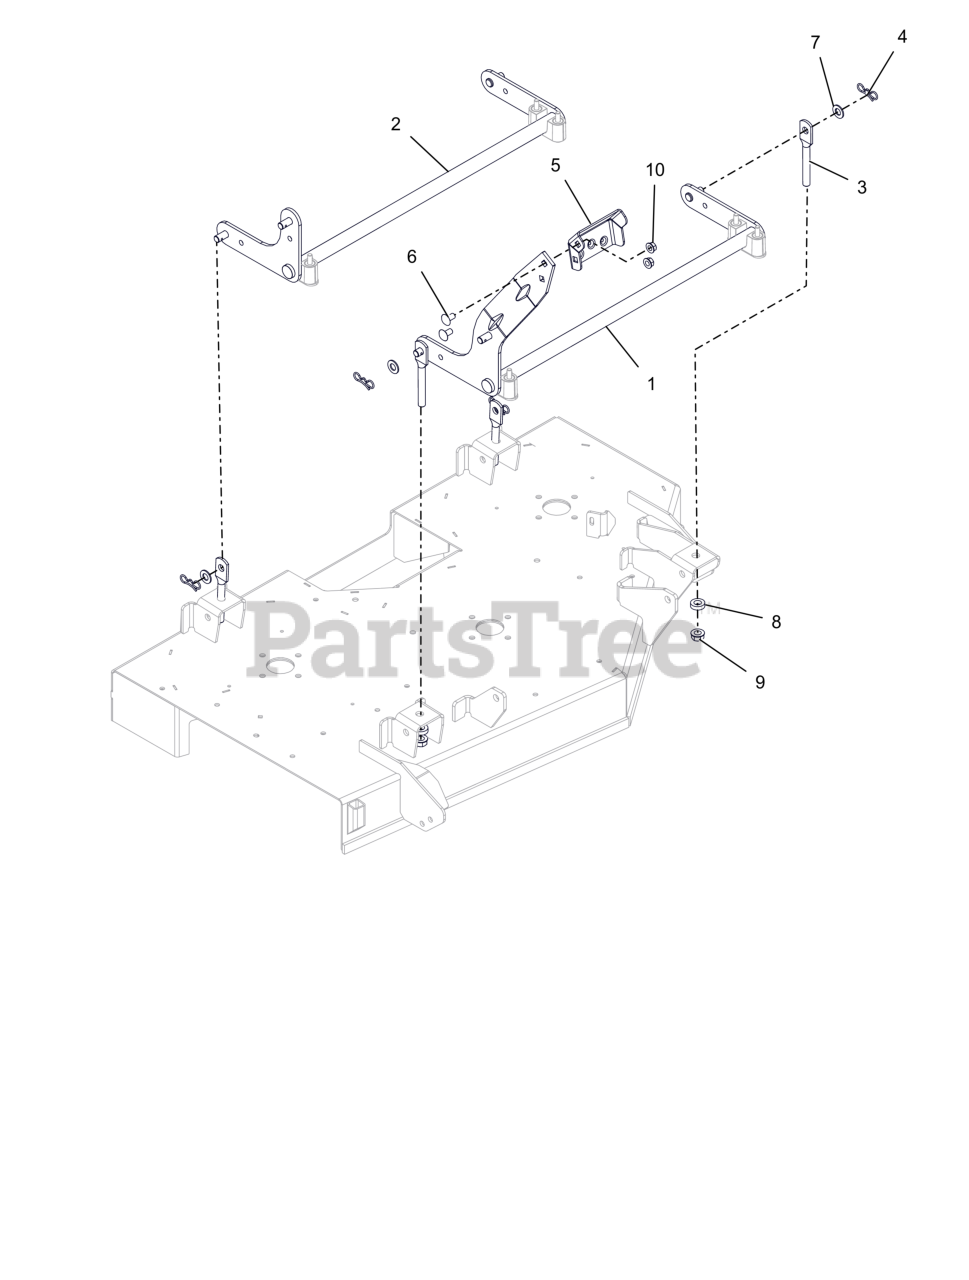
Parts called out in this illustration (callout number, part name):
1	WLDMT, FRONT DECK LIFT PIVOT
2	WLDMT, REAR DECK PIVOT
3	LINK, DECK (HOLE-LONG)
4	PIN, BOWTIE .091X1.875 ZCC
5	PEDAL, DECK LIFT (BOLT ON)
6	BTL,RHSSN .375-16 X 0.75 G5 FPB
7	WSHR-FL-NYL .518X1.000X.080
8	WSHR, RUBBER
9	NUT-LK-CTR-FLG .500-13 GG ZCC
10	NUT-LK-CTR-FLG .375-16 GF ZCC
